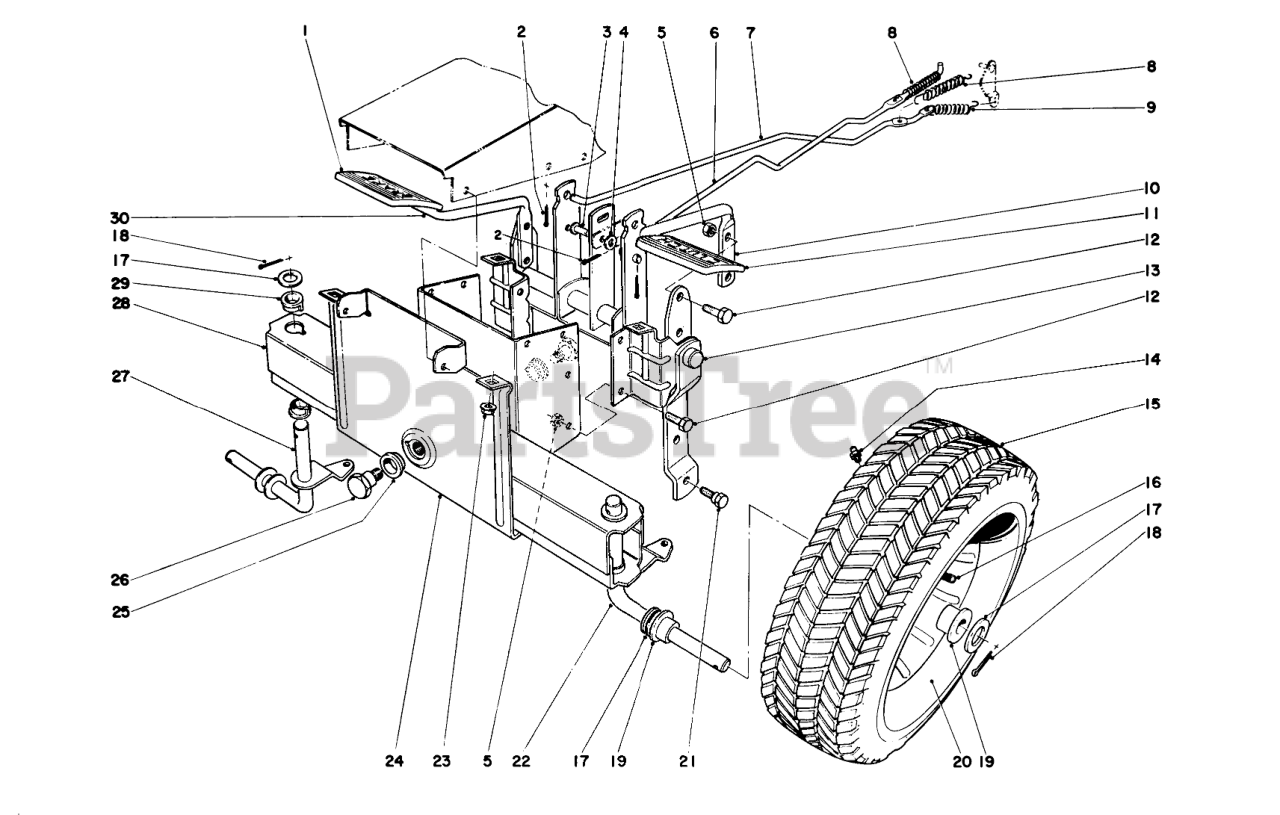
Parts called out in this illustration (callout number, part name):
1	PAD-BRAKE
2	PIN-COTTER
3	PIN-CLEVIS
4	WASHER-PLAIN
5	NUT-LOCK, CONE
6	Clutch Rod
7	Rod Brake
8	Spring
9	Spring, Brake
10	Clutch Pedal
11	CLUTCH PAD
12	SCREW-HH
13	Control Shaft
14	FITTING-GREASE
15	Tire Turf King
16	STEM-VALVE
17	WASHER-FLAT
18	PIN-COTTER
19	BUSHING
21	Screw
22	Spindle L.H.
23	NUT-HF
24	Frame Lower Front
25	Bushing
27	Spindle R.H.
28	Front Axle
29	Bushing
30	Brake Pedal
